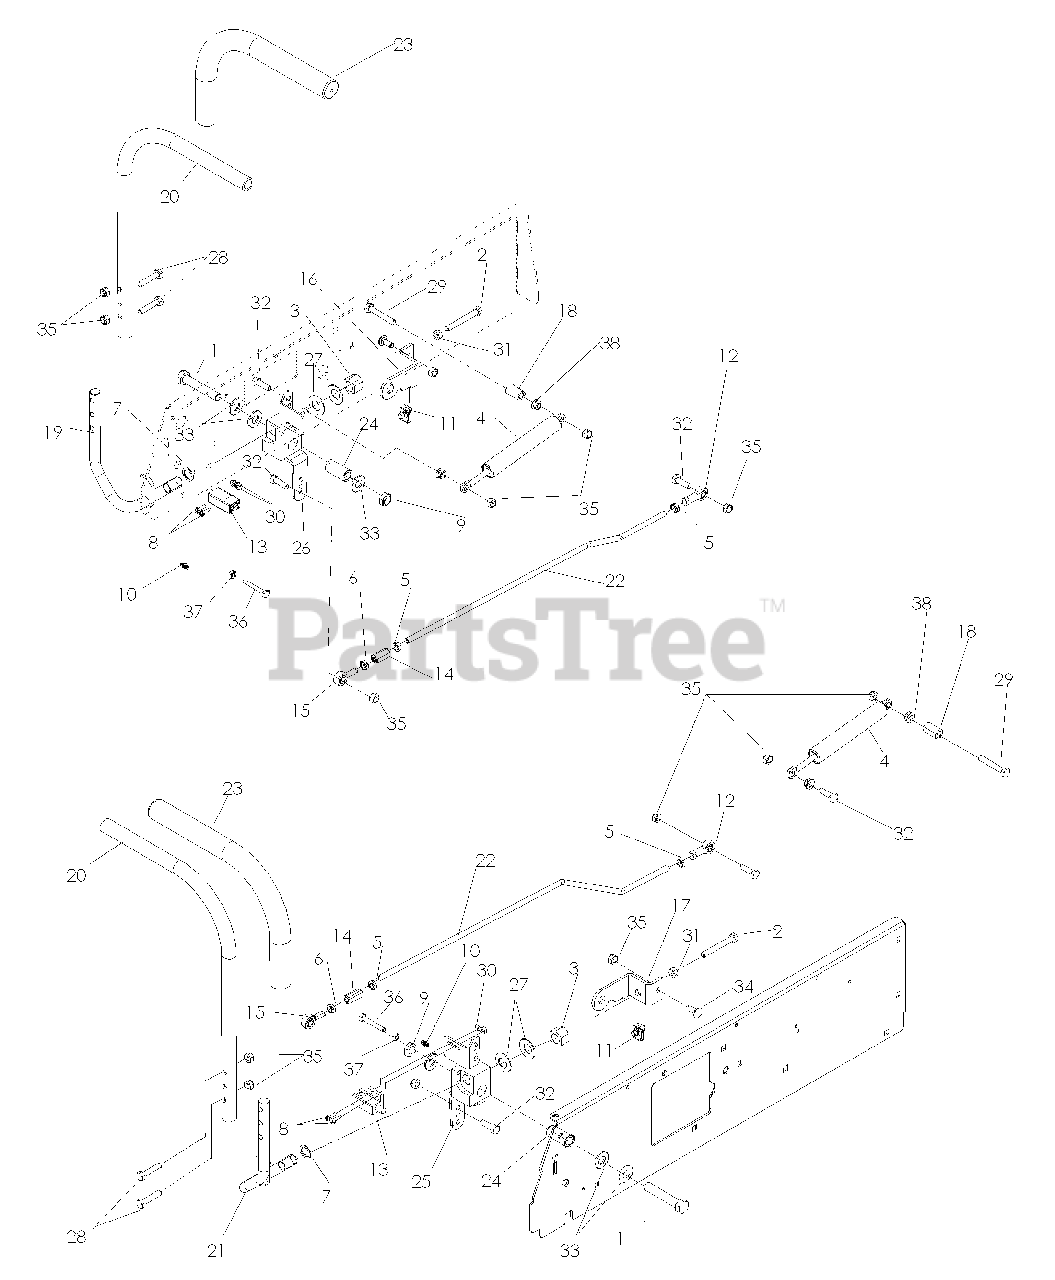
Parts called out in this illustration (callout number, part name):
1	HCS 1/2C X 2 3/4
2	HCS 5/16-18 X 2 1/2 TPBLT
3	NUT 5/8-11 NYLOC
4	DAMPENER, DUAL ACTION
5	NUT 5/16-24 UNF HEX JAM
6	NUT 5/16F LEFTHAND
7	WASHER-.626IDX.056TK
8	SCREW #10-24 X 5/8
9	NUT 1/2-13 HEX JM NYL
10	ZERK, 3/16, DRIVE IN
11	U-CLIP 5/16-18 NUT RETAINER
12	RH ROD END
13	SWITCH, INTERLOCK
14	ROD END COUPLER
15	ROD.END.LH
16	FORWARD STOP RH
17	FORWARD STOP LH
18	BUSHING
19	LEVER.PLATED.RH
20	LEVER UPPER
21	LEVER PLATED LH
22	CONTROL ROD
24	BUSHING
25	PIVOT LH (PLATED)
26	PIVOT RH (PLATED)
27	WASH 5/8 BEVELED DISC SPRING
28	CAPSCREW 5/16 X 1/1/2 HEX HEAD
29	HCS 5/16-18X2
30	NUT 10-24 NYLOC
31	NUT 5/16C HEX
32	HCS 5/16C X 1
33	WASHER 1/2" FLAT
34	BOLT 5/16C X 3/4" CARRIAGE
35	NUT 5/16 NYLOC
36	BOLT 1/4C X 1 3/4
37	NUT 1/4-20 JAM
38	5/16-18 FLANGED L-NUT
